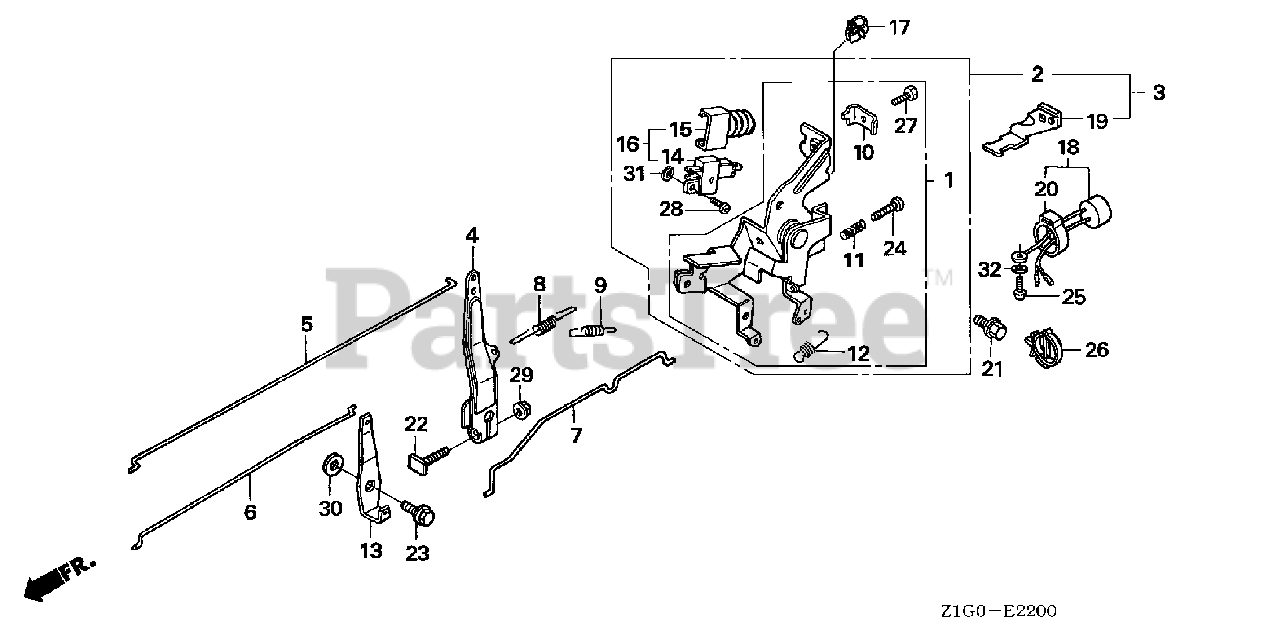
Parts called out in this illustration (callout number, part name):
3	CONTROL ASSY. (ALT)
4	ARM, GOVERNOR
5	ROD, GOVERNOR
6	ROD, CHOKE
7	ROD, JOINT
8	SPRING, GOVERNOR
9	SPRING, GOVERNOR PRIMARY
10	HOLDER, CABLE
11	SPRING, CONTROL ADJUSTING
12	SPRING, CABLE RETURN
13	LEVER, CHOKE JOINT
14	SWITCH ASSY., ENGINE
15	COVER, SWITCH
16	SWITCH ASSY., ENGINE STOP
17	HOLDER, STOP SWITCH WIRE
18	BUZZER ASSY.
19	STAY, BUZZER
20	SUSPENSION, AUDIBLE PILOT
21	BOLT, FLANGE (6X12) (CT200)
22	BOLT, GOVERNOR ARM
23	BOLT, FLANGE (6MM)
24	SCREW, PAN (5X20)
25	SCREW, TAPPING (5X8)
26	CLIP, HARNESS
27	BOLT, RECESSED (5X16)
28	SCREW, PAN (4X14)
29	NUT, FLANGE (6MM)
30	WASHER, PLAIN (6MM)
31	WASHER, SPRING (4MM)
32	WASHER, SPRING (5MM)
